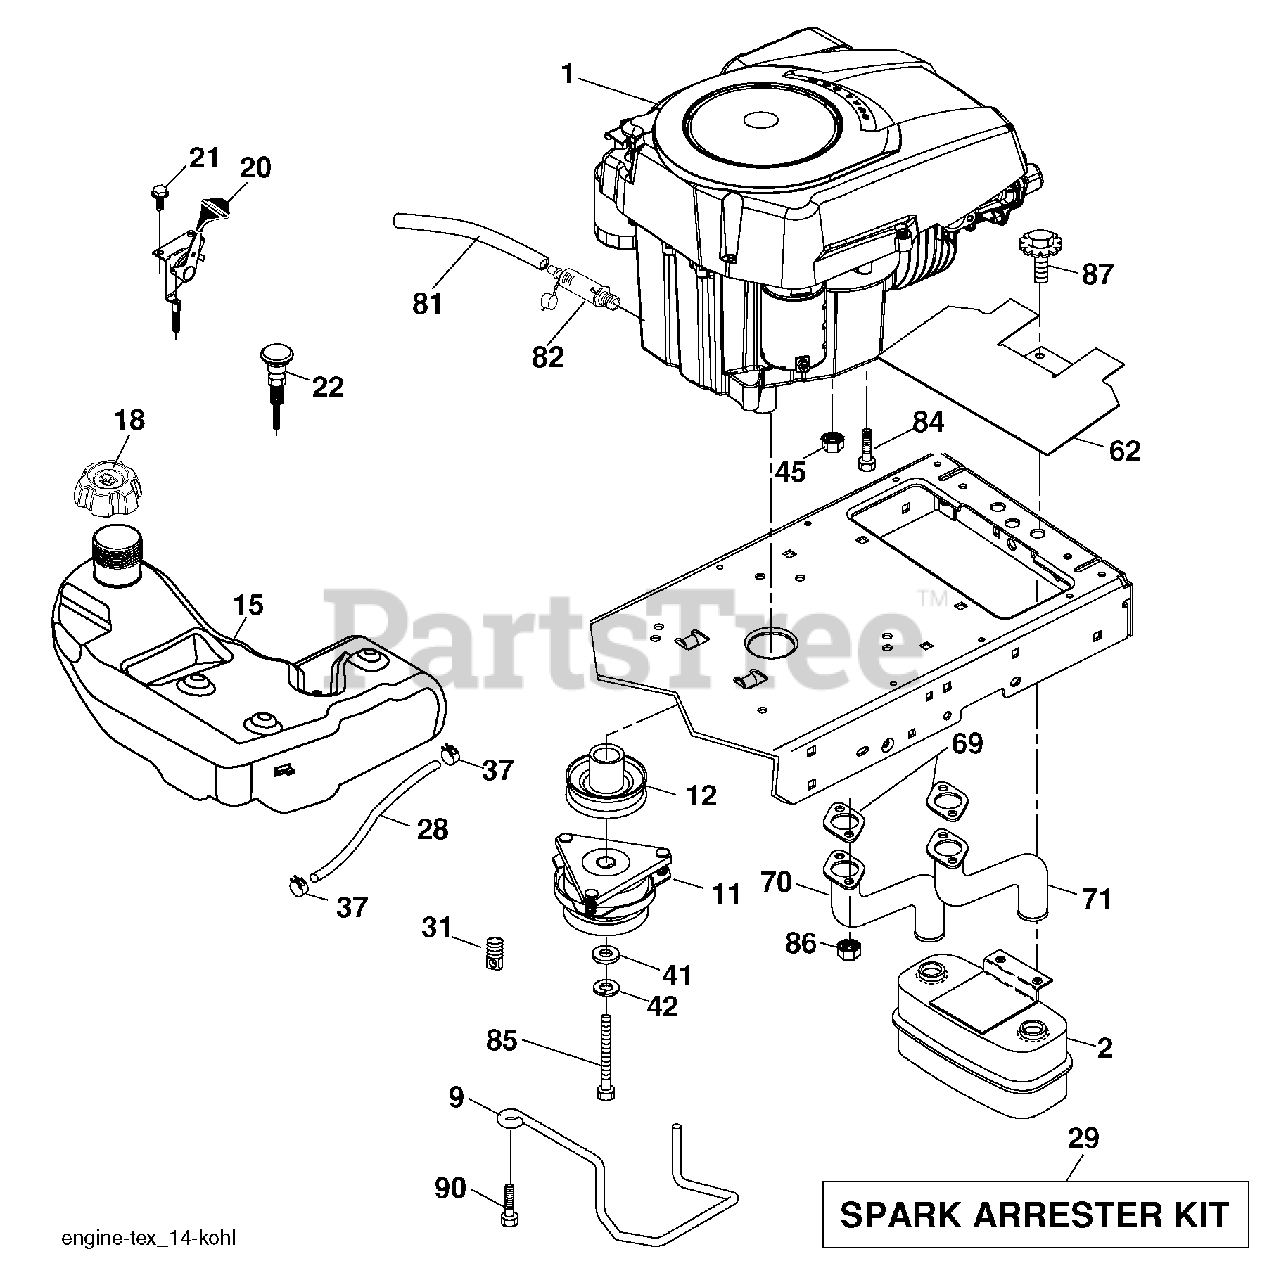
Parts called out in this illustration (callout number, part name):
2	Muffler
9	Keeper Asm. Belt Engine
11	Clutch Electric
12	Pulley Engine
15	Tank Fuel 4.0
18	Cap Asm
20	Control Throttle
21	Screw 10 x 3/4 Single Lead-Hex
22	Control Choke
28	Fuel Line
29	Spark Arrester Kit
31	Clip Push-In Hinged
37	Clamp Hose
41	Washer 1-1/2 OD x 15/32 ID x .250
42	Washer Lock 7/16
45	Nut Keps Hex 1/4-20 unc
62	Shield Heat Muffler
62	Gasket
70	Tube Exhaust LH
71	Tube Exhaust RH
81	Tube Drain Oil Easy
82	Plug Drain Oil
84	Screw 3/8-16 x 1-1/2
85	Bolt Hex 7/16-20 x 3.75 Gr. 5
86	Nut Flange Toplock M8-1.25
87	Bolt 5/16-18 unc x 1 w/Sems
90	Screw 3/8-16 x 1
